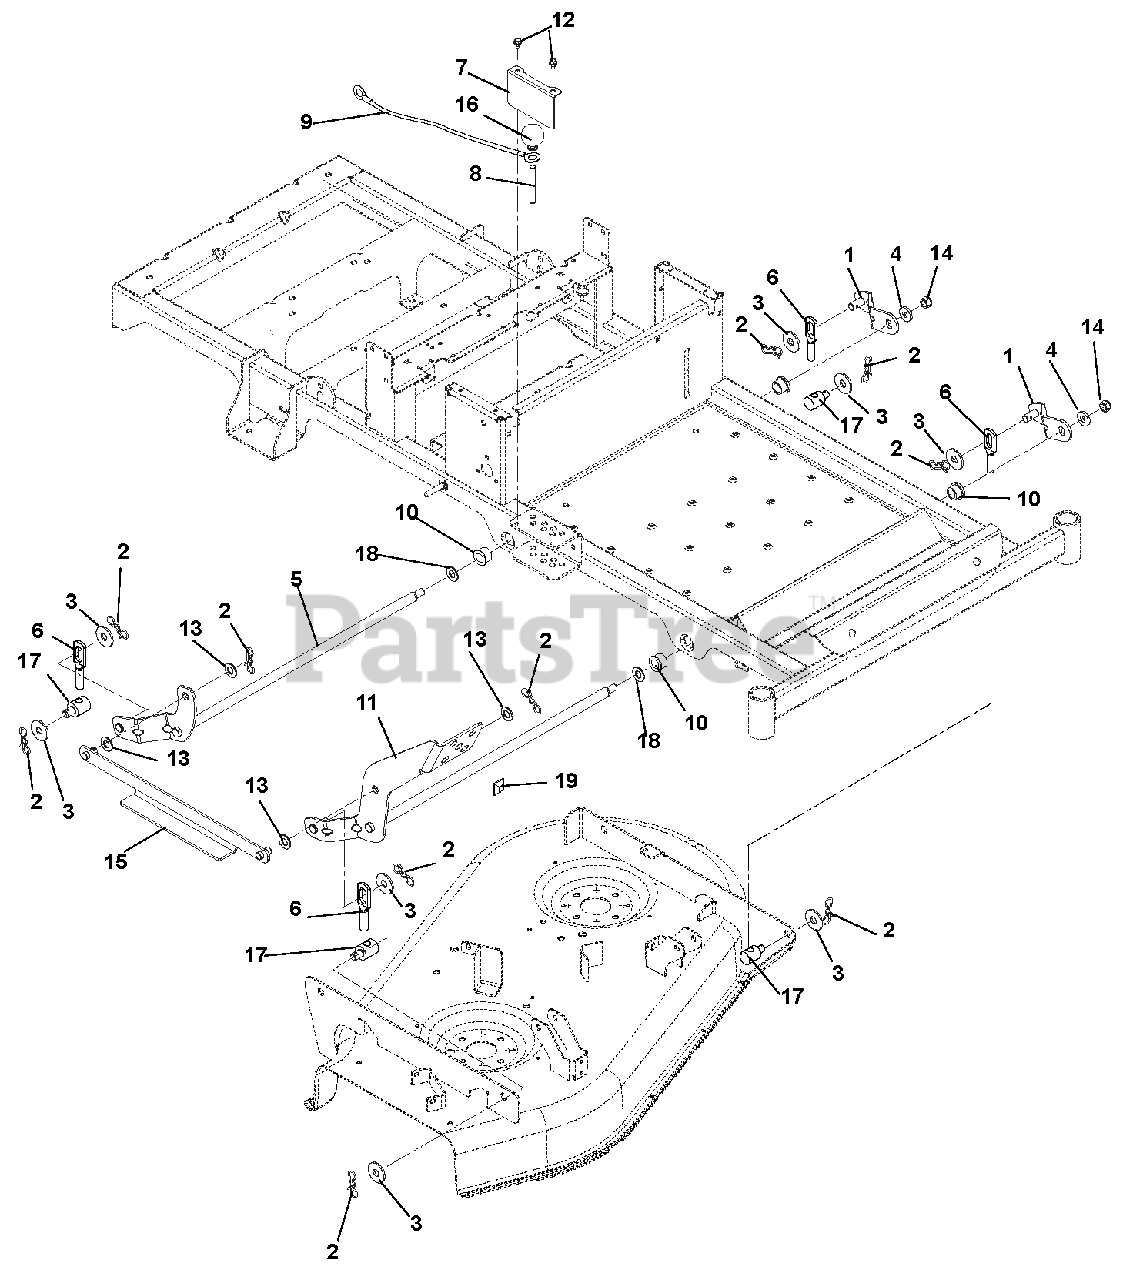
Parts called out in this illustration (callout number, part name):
1	WMT, LIFT ARM
2	PIN,BOW TIE LOCKING .091X1.875
3	WSHR-FL-STL.511X1.441X.125 YWZ
4	WSHR-FL-STL .50X1.25X.160 YWZC
5	WMT, REAR DECK LIFT SHAFT
6	DECK LINK
7	GUARD, DECK LIFT
8	PIN, DECK
9	CABLE, 12.0 LANYARD, NYLON
10	BSHG-FLG .629X.879X.469X1.250
11	WMT, DECK LIFT PEDAL
12	@SCR-TAP .25-20X.37 HWH YWZ TR
13	WSHR-FL-NYL .518X1.000X.080
14	NUT-LK-NYL .44-20 YWZC
15	WMT, LIFT LINK
16	KNOB,BALL -BLACK 1.47" .375-16
17	TRUNNION-.50
18	@WSHR-FL-STL.656X1.31X.095 YWZ
